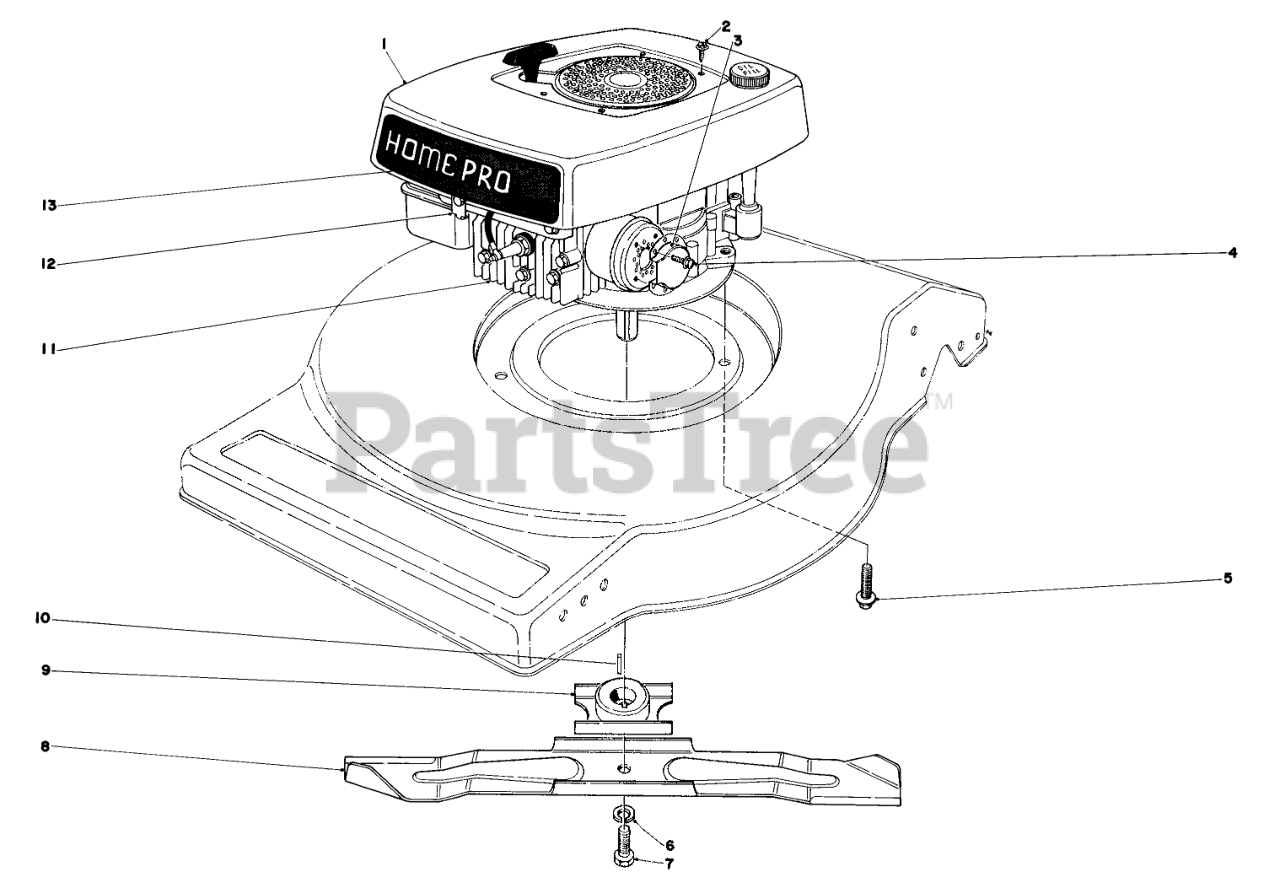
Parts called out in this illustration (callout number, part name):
1	Shroud
2	8X1/2 SELF TAP SCREW
3	Deflector
4	SCREW W/ENGINE
5	SCREW-HWHTF
6	WASHER-LOCK
7	SPECIAL SCREW
8	Blade
9	Blade Retailer
10	KEY-SQUARE
11	Engine
12	Bracket Control
13	Decal Shroud
